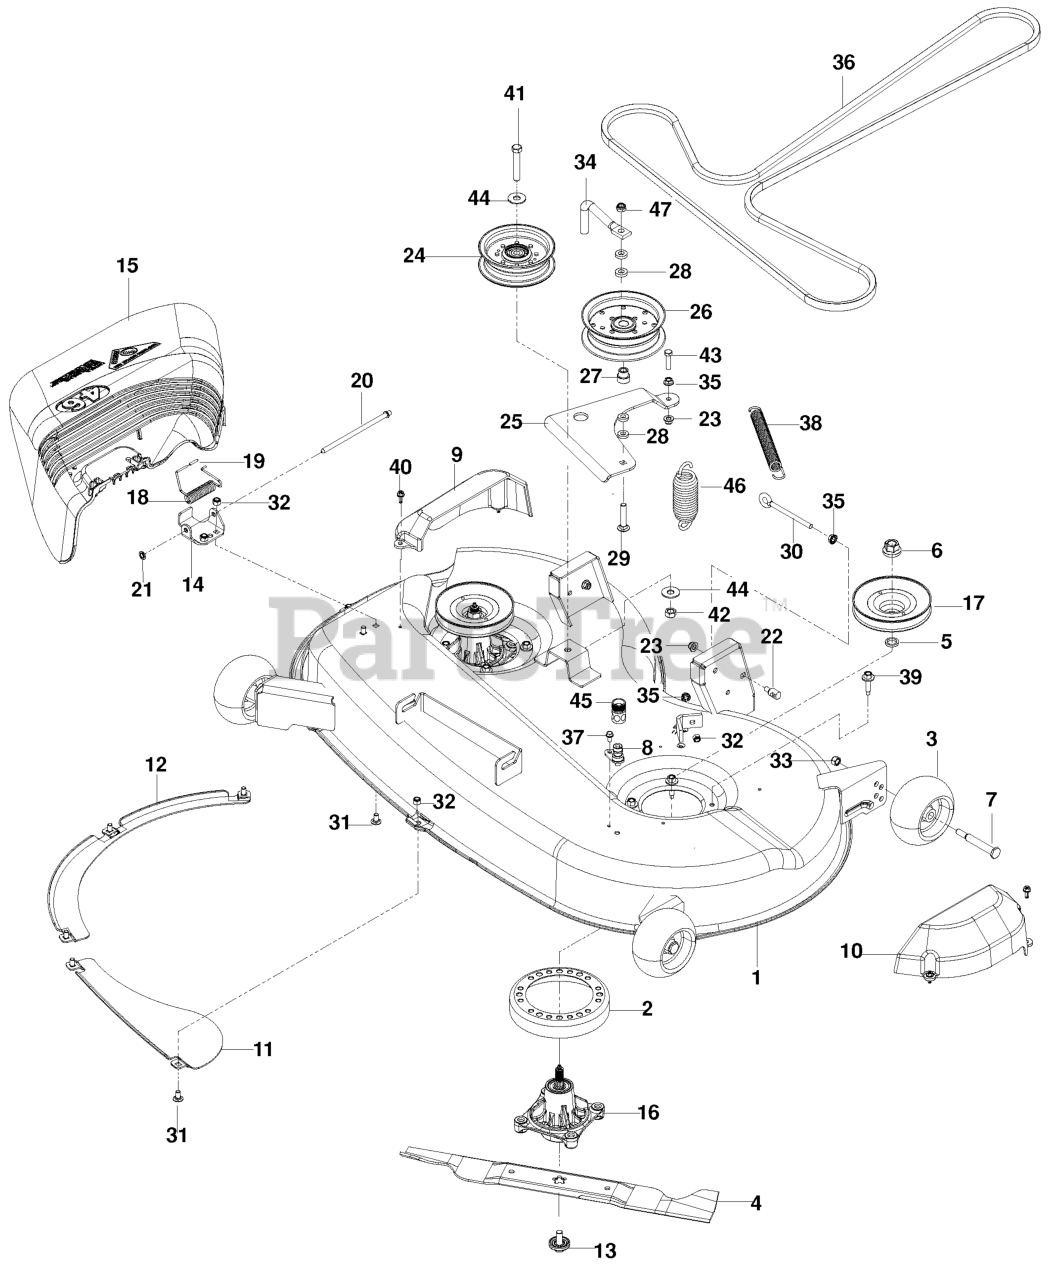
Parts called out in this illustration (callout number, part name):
1	DECK W/DECALS - RZ46
2	STRIPPER-ROUND-UNIVERSAL
3	GAUGE WHEEL
4	BLADE.MOWER.46".HI.LIFT
5	WASHER-SPACER
6	LOCKNUT - 9/16
7	SHOULDER BOLT 1/2X2-5/8 ZD SPE
8	PORT.WASHOUT
9	COVER.MANDREL.RH.46"
10	COVER.MANDREL.LH.46"
11	BAFFLE CENTER FRONT
12	BAFFLE FRONT RH
13	BOLT.WASHER.ASM.7/16-2
14	BRKT.DEFLECTOR.38"2005+
15	SHIELD.DEFLECTOR.MOWER.46"BLAC
16	CUTTER HOUSING
17	RP.PULLEY, DECK
18	TORSION SPRING
19	CAP-SLEEVE
20	ROD, HINGE
21	PUSH NUT
22	STUD.FASTNER.W/ANTI-ROTATE
23	5/16-18 NYLOC FLANGE NUT
24	PULLEY.IDLER.MWR.STATI.LH
25	ARM, IDLER BLK
26	PULLEY, IDLER
27	IDLER BUSHING
28	WASHER 3/8 X 3/4 X .187 TK
29	CARRIAGE BOLT 3/8-16 X
30	EYE BOLT 5/16 X 3.50
31	BOLT 5/16C X 3/4" CARRIAGE
32	NUT 5/16 NYLOC
33	NUT 3/8-16 NYLOC
34	BELT KEEPER 5"
35	NUT 5/16C WHIZ
37	BOLT 1/4-20 X 1/2 HWST
38	SPRING, DECK BELT
39	WASHER HEAD SCREW
40	SCREW- 1/4-20 X 5/8
41	BOLT 7/16-14 X 2-1/2 GR 5 ZD
42	7/16-14 HEX NUT W/NYL RING ZD
43	HCS 5/16C X 1 1/4
44	WASHER 7/16 FLAT ZD
45	COUPLING.QUICK CONNECT
46	SPRING
47	NUT HEX 3/8-16 NYLON, THIN
